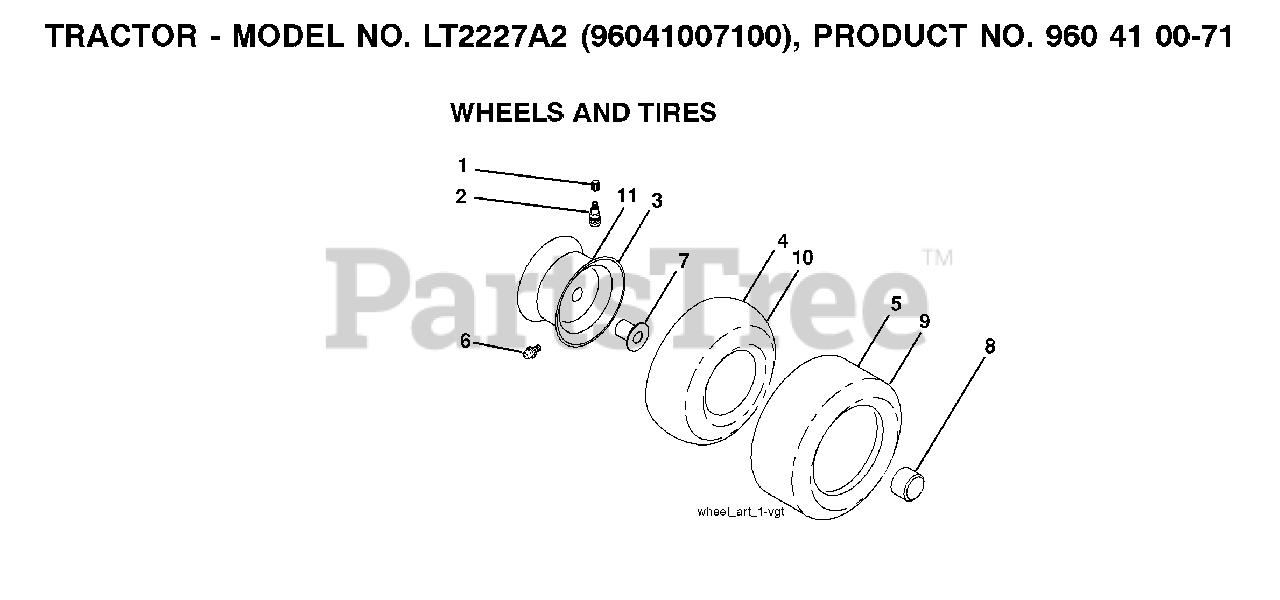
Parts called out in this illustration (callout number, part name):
1	VALVE CAP
2	VALVE STEM LT
3	RIM ASSEMBLY, FRONT
4	TUBE.16X6.5/7.5-8
5	TIRE HEAVY DUTY
6	FITTING LT
7	BEARING T
8	CAP, AXLE BLK
9	TIRE HEAVY DUTY
10	TUBE 23X950X12
11	RIM ASSEMBLY, REAR
